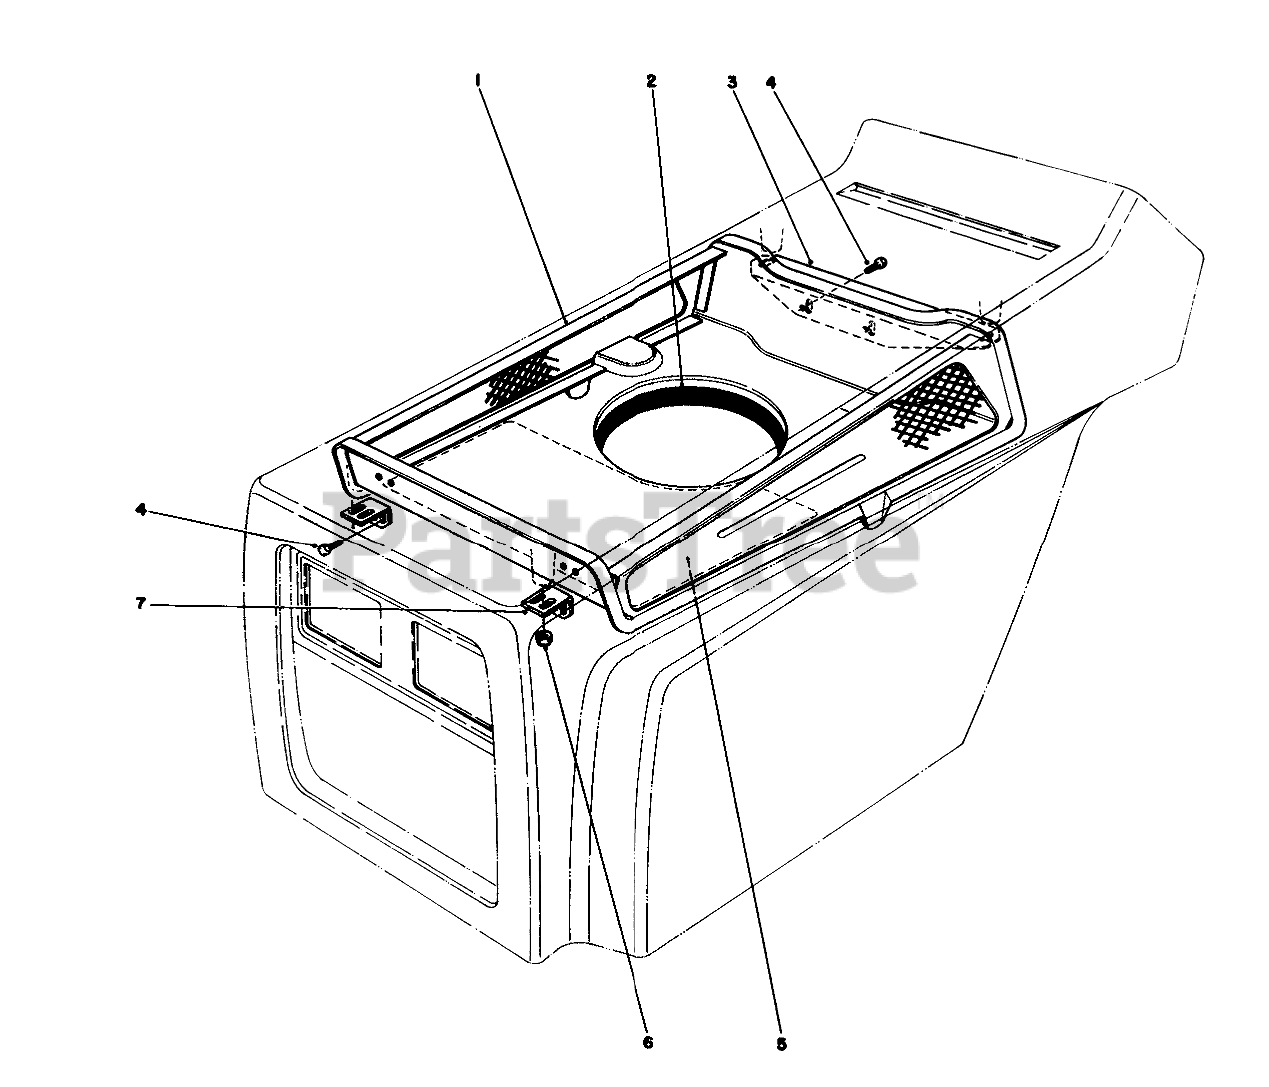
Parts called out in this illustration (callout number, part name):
1	Duct Hood
2	Seal Engine
3	Bracket Rear Duct Support
4	SCREW-HWHTF
5	Decal Service
6	NUT-LOCK, NI
7	Bracket Front Duct Support
